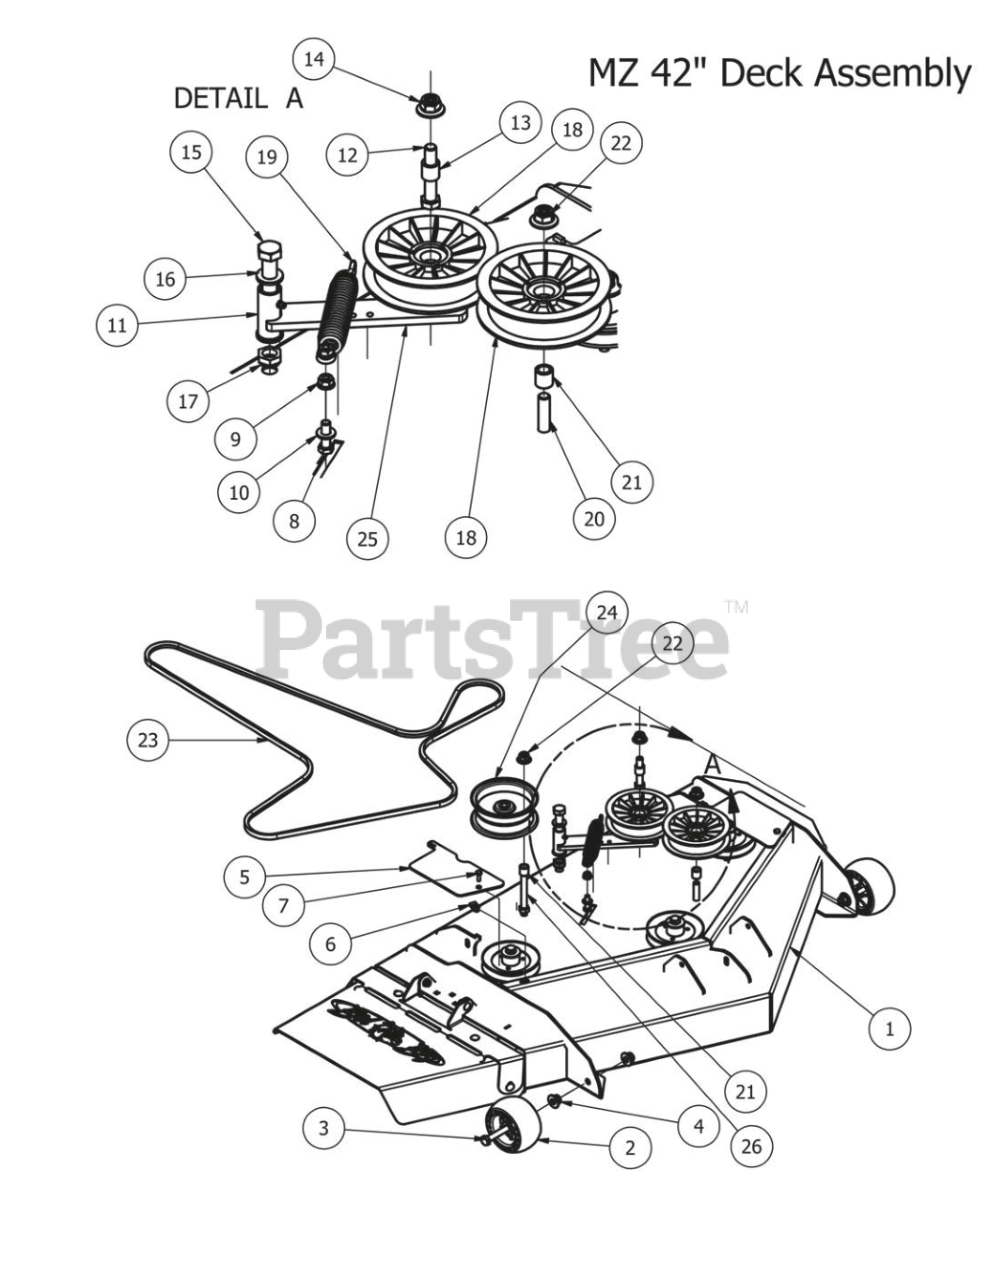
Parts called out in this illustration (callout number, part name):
1	Mz 42 Deck
2	Deck Wheel
3	1/2 x 3 1/2 Flange Bolt Grade 8
4	1/2-13 Nylon Flange Nut-Orange
5	MZ42 Pulley Cover
6	1/4-20 Cage Nut
7	1/4" x 3/4" Hex Bolt
8	3/8" x 1 1/4" Hex Bolt
9	3/8" Nylock Flange Nut
10	3/8" Flat Washer
11	Deck Idler
12	1/2" x 2 3/4" Hex Bolt
13	3/4 OD x 1/2 ID x 3\4 Length
14	1/2-13 Nylon Flange Nut-Orange
15	5/8" x 4" Hex Bolt
16	.635 ID Plastic Washer
17	5/8" Nylock (1/2 Jam)
18	Plastic Idler Pulley
19	Deck Idler Spring MZ
20	1/2" x 2 3/4" Hex Bolt
21	3/4 OD x 1/2 ID x 3\4 Length
22	1/2-13 Nylon Flange Nut-Orange
23	42" Deck Belt-B120
24	5 3/4" Deck Idler Pulley
25	Parts 11,12,13,14,18 make up the deck idler assembly
26	1/2-13 x 3 1/2 GR 5 Hex Bolt
